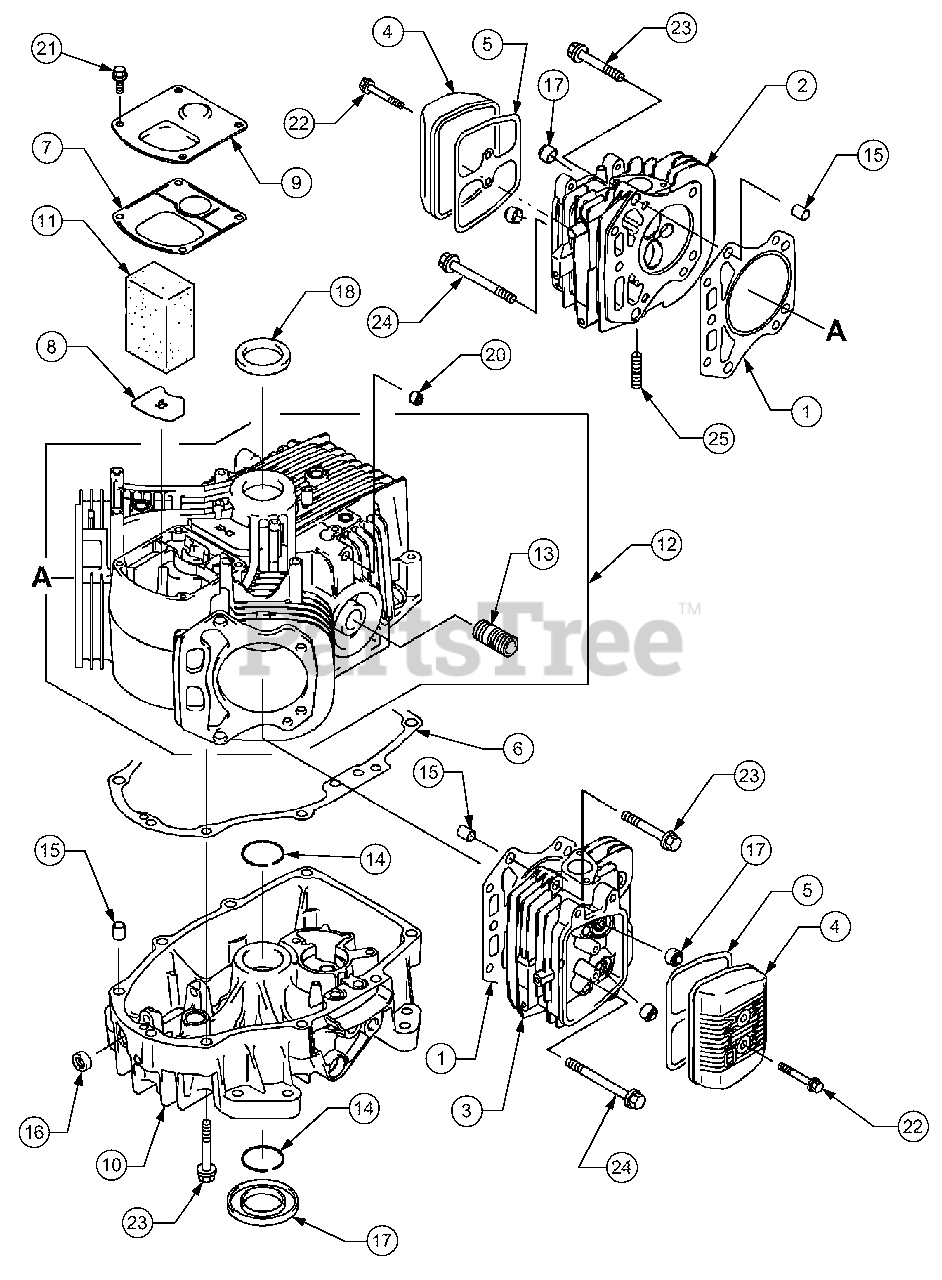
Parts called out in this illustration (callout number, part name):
1	Gasket, Head
2	Head, Comp Cylinder
3	Head, Comp Cylinder
5	Gasket, Rocker Case
6	Gasket, Crankcase Cover
7	Gasket, Breather
9	Cover
10	COVER-CRANKCASE
11	Element, Breather
12	Crankcase, Comp
16	Seal, Oil, SO 8x14x5 HS
17	Seal, Oil, 6x11x10.4
18	Seal, Oil, SD 35-48-8 R HS
21	Bolt, Flanged
22	Bolt, Flanged
23	Bolt, Flanged
24	Bolt, Flanged
25	Bolt, Stud
